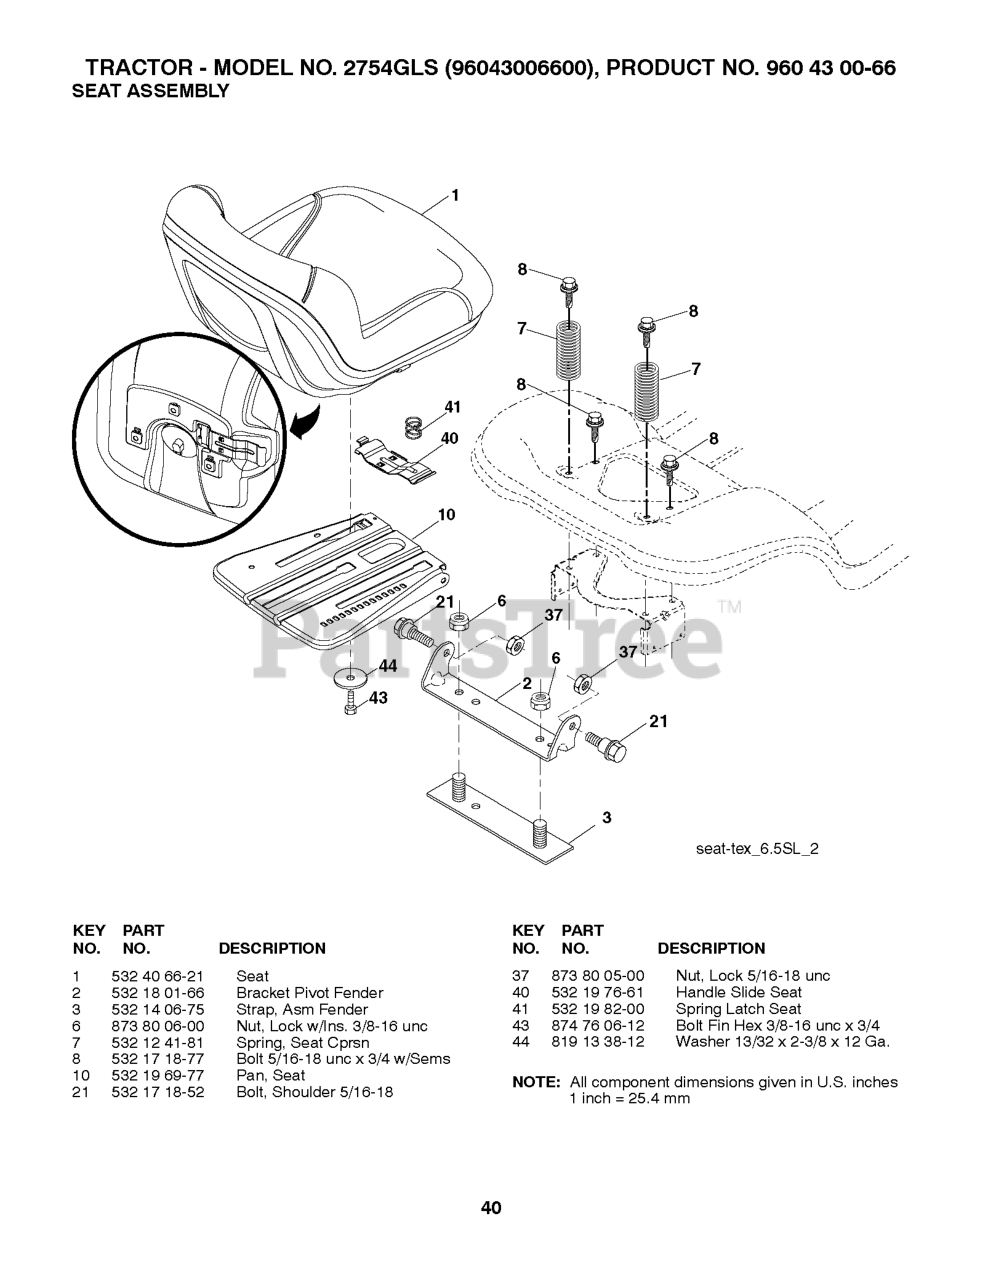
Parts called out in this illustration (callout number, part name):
1	SEAT - GREY
2	BRKT.PIVOT.FENDER
3	STRAP
6	NUT
7	SPRING COMPRESSION
8	BOLT.5/16-18UNCX3/4 W/SEMS.BLK
10	PAN.ASM.SEAT.3PT
21	BOLT.SHOULDER.5/16-18
37	NUT.71038.31-18.HEX.NYLOCK
40	HANDLE.SLIDE.SEAT.TEX.BLACK
41	SPRING.LATCH.SEAT.TEX
44	WASHER 13/32 X 2-3/8 X 12GA
